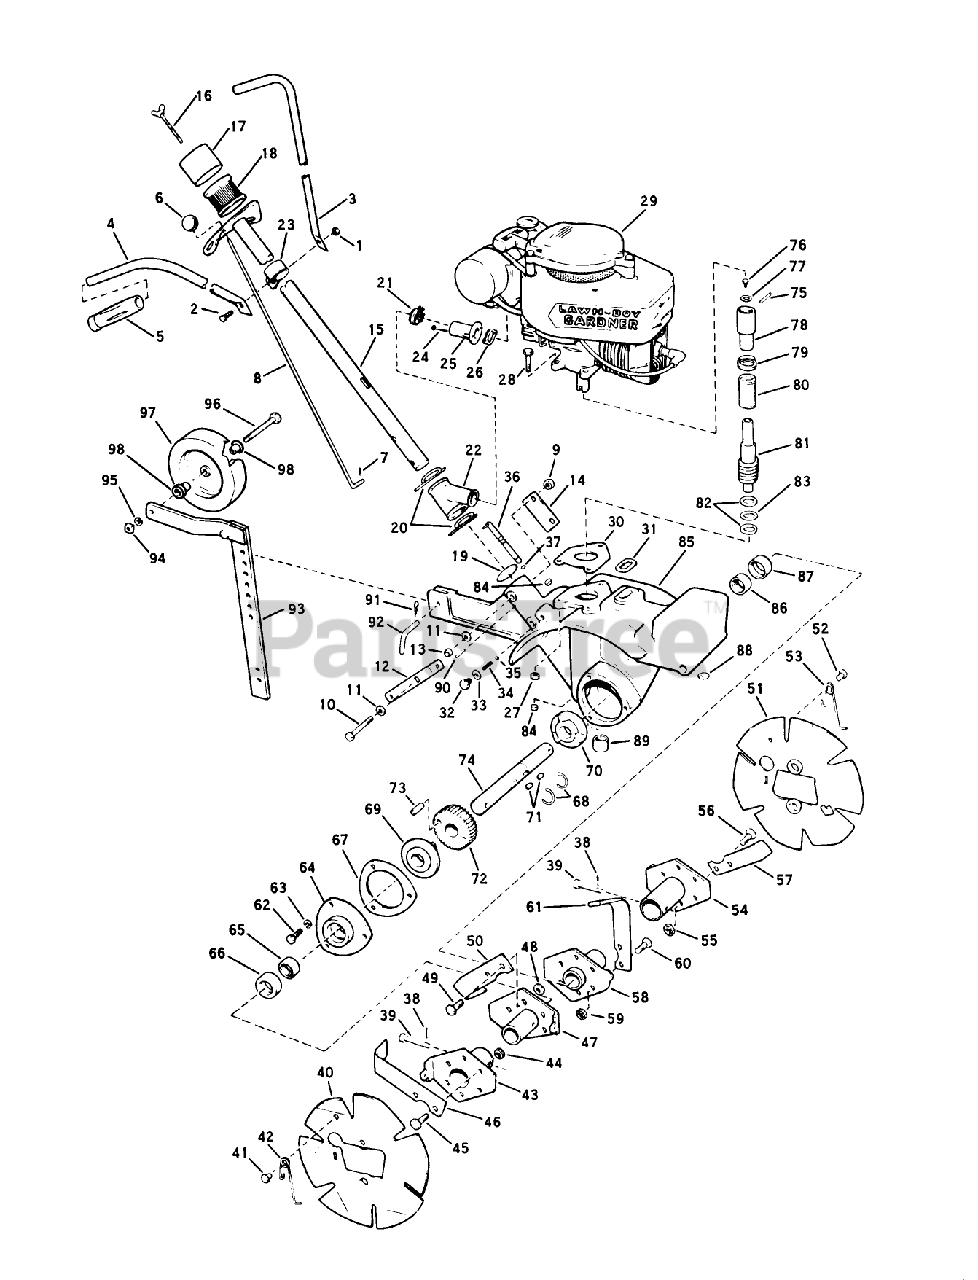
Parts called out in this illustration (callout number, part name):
3	Handlebar Section-Left
4	Handlebar Section-Right
6	Knob-Control Rod
7	Cotter Pin
8	Rod-Control
9	LOCKNUT
10	Screw-Hex Head Cap
12	Cotter Pin
13	Spacer-Control Rod Lever
14	Clamp-Handlebar Support Tube
19	Seal-Dust, Felt
20	Clamp-Hose
22	Tee-Carburetor, Rubber
23	Clamp-Handlebar
25	Tube-Carb. to Handle
32	Screw-Hex Head, Nylok
33	Washer-Plain, Aluminum
34	Spring-Detent
35	Ball-Detent
36	Clutch Pin Control Assy.
37	Ring-"O", Clutch Pin
39	Pin-Tine Assy. Attachment
41	Rivet-Shoulder
42	Spring-Trim Plate, Right
45	Screw-Hex Head Cap
46	Tine-Right Hand
49	Screw-Hex Head Cap
50	Tine-Right Hand
52	Rivet-Shoulder
53	Spring-Trim Plate, Left
56	Screw-Hex Head Cap
57	Tine-Left Hand
60	Screw-Hex Head Cap
61	Tine-Left Hand
65	Bearing
67	Gasket-Housing Cover
68	Ring-Retaining
70	Ratchet-Clutch, Left
72	Gear-Worm
73	Pin-Ratchet
74	Shaft-Worm Gear
75	Pin-Clutch
76	Screw-Hex Head, Nylok
77	Washer-Thrust
78	Coupling-Clutch Drum
79	Spring-Clutch Shock
82	Race-Thrust
83	Bearing-Needle Thrust
86	Bearing
89	Bearing-Closed End
92	Pin-Selector
95	WASHER, LOCK
